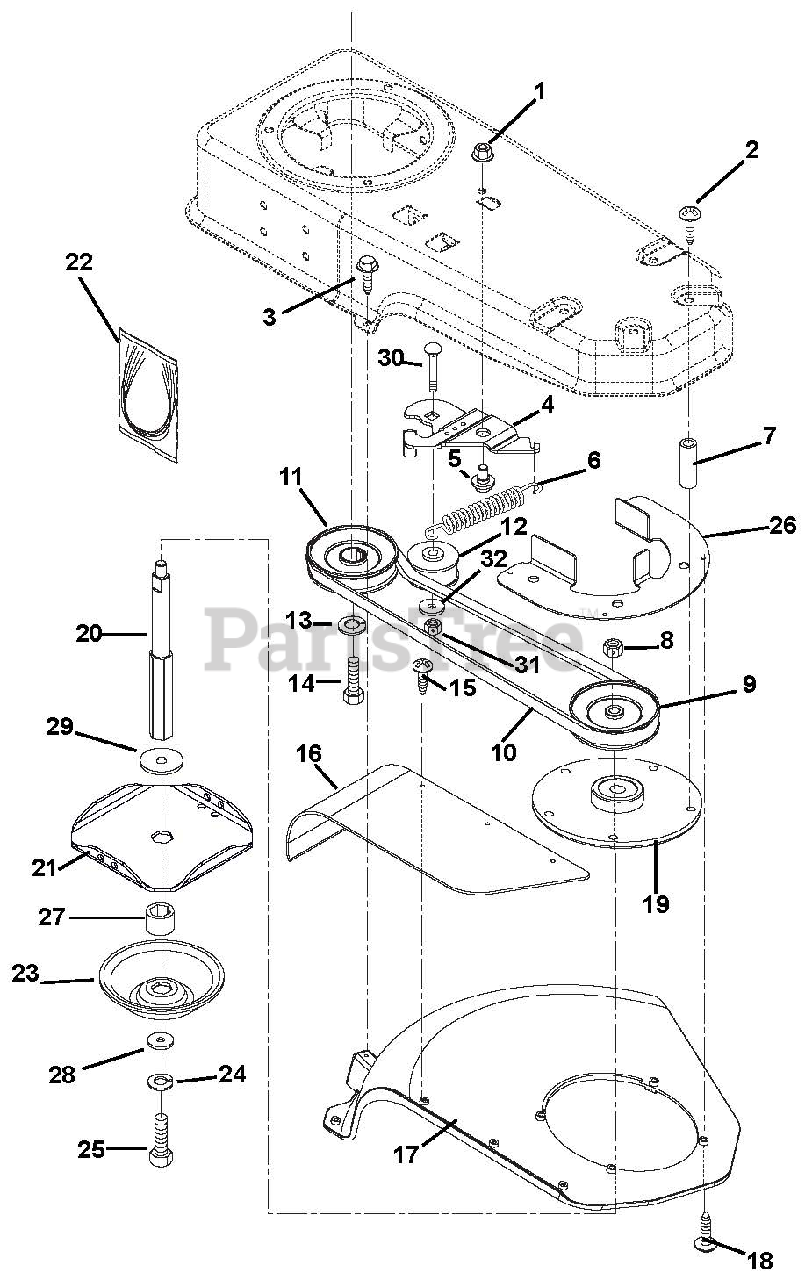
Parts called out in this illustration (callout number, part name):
1	Nut, Locking Flange .38-16
2	Screw, Tapping .38-16 x 2.75
3	Screw, Tapping 10-24 x .75
4	Bracket, Idler
5	Bolt, Shoulder .38-16 x .135
6	Spring, Tension .035 x .45 x 2.75
7	Spacer, Jackshaft
8	Nut, Locking Flange .38-24 Grade 5
9	Pulley, V 3.50 O.D. x .87 Wide
10	Belt, V A-RMA 46.06 x .50
11	Sheave, Engine 3.50 O.D. x .87 Wide
12	Idler, Flat 1.88 O.D. x .75 Wide
13	Washer, Locking .38 x .94 Regular
14	Bolt, Hex .38-24 x 1.00
15	Screw, Tapping 10-16 x .625 Hex Washer Head
16	Guard, Debris
17	Shield, Trimmer
18	Screw, Tapping 10-24 x .75
19	Housing, Jackshaft
20	Shaft, Cutter Hex
21	Disc, Cutter
22	Line, Cutter 18"
23	Guide, Height Hex
23	Guide, Height Long Life
24	Washer, Locking .31 x .078
25	Bolt, Hex .31-18 x .75 Grade 5
26	Finger, Belt
27	Spacer, Hex
28	Washer, Flat Steel .344 x 1.13 x .135
29	Shield, Dust
30	Bolt, Round Head Short Square Neck .38-16 x 1.50 Grade 5
31	Nut, Locking Center .38-16
32	Washer, Flat Steel .406 x .812 x .065
